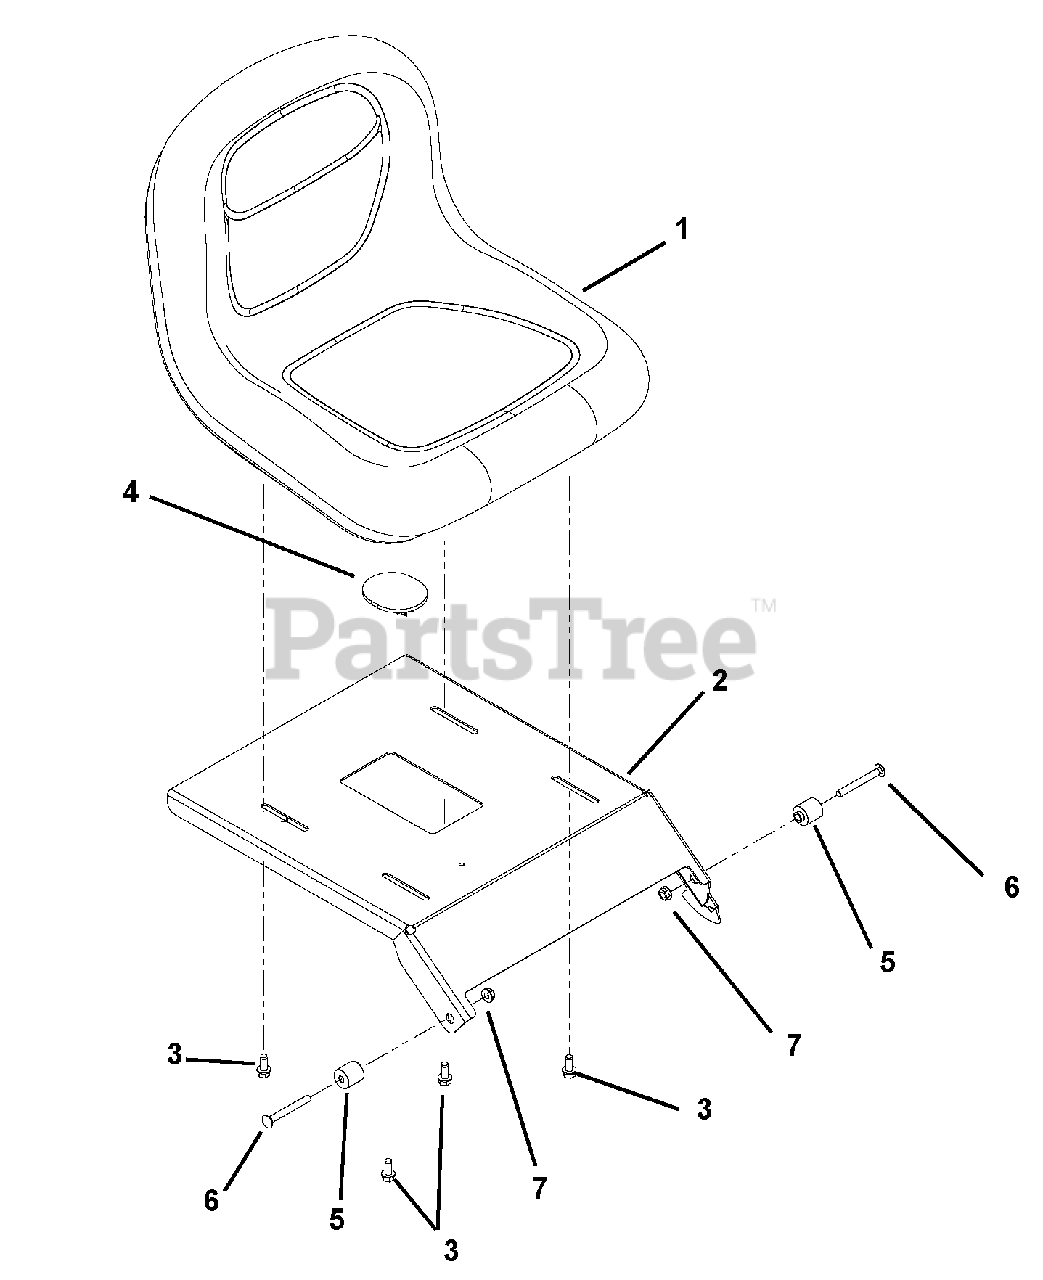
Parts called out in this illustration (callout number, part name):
1	SEAT, MILSCO XB150 GRAY
2	WMT, SEAT PLATE
3	5/16-18X3/4 HX/W/HD WHIZ
4	SWITCH- SEAT
5	SPCR, FLG .32X.49X.192X1.00
6	BLT-RDHDSQSHNK.31-18X2.75G2YWZ
7	@NUT-LK-TOP-FLG .31-18 YWZC
